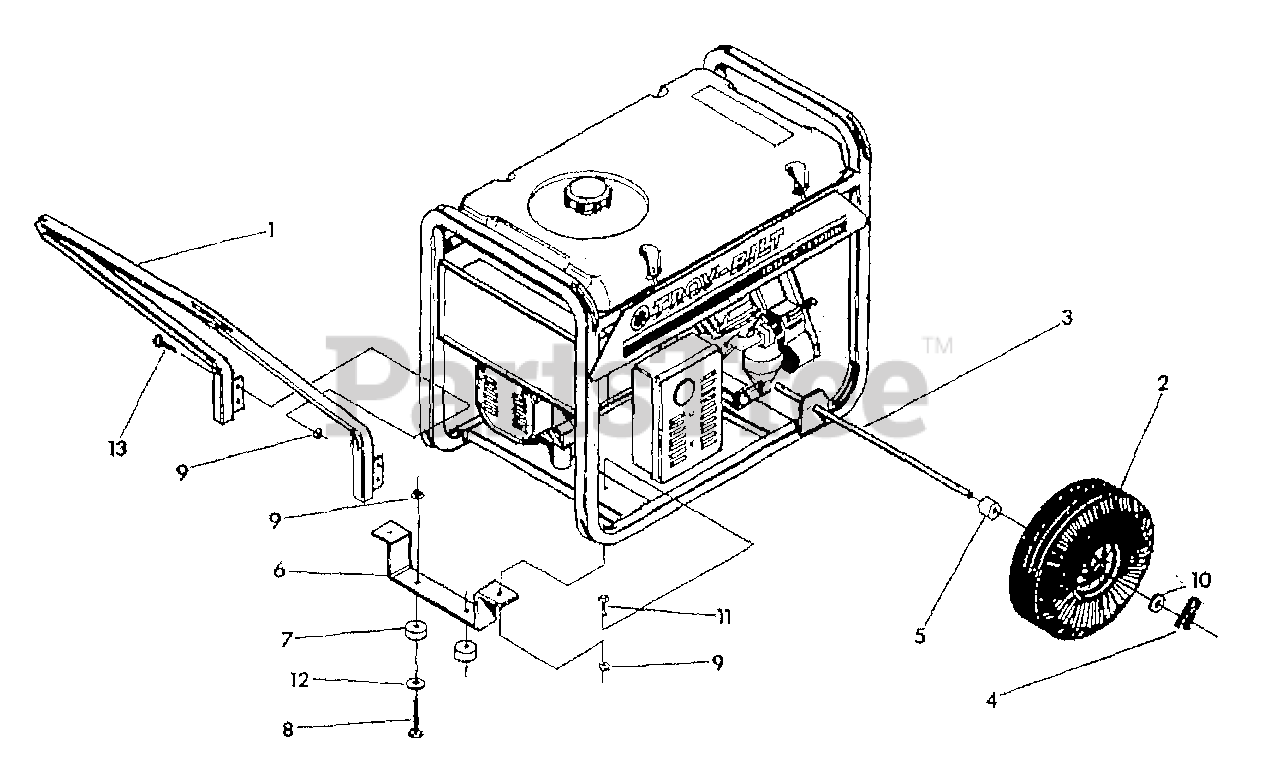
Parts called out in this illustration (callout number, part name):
1	HANDLE (4000W GENERATOR)
3	AXLE (4000W GENERATOR)
4	PIN-RETAINING
5	SPACER
7	MOUNT-VIBRATION
8	SCR-HH M8-1.25X30MM
9	NUT-HF/LK M8-1.25
10	WASHER-WHEEL (GENERATOR)
11	SCR-HH M8-1.25X20MM
12	WASHER-M8 VIBRATION MOUNT
13	SCR-CAP M8-1.25X45MM
